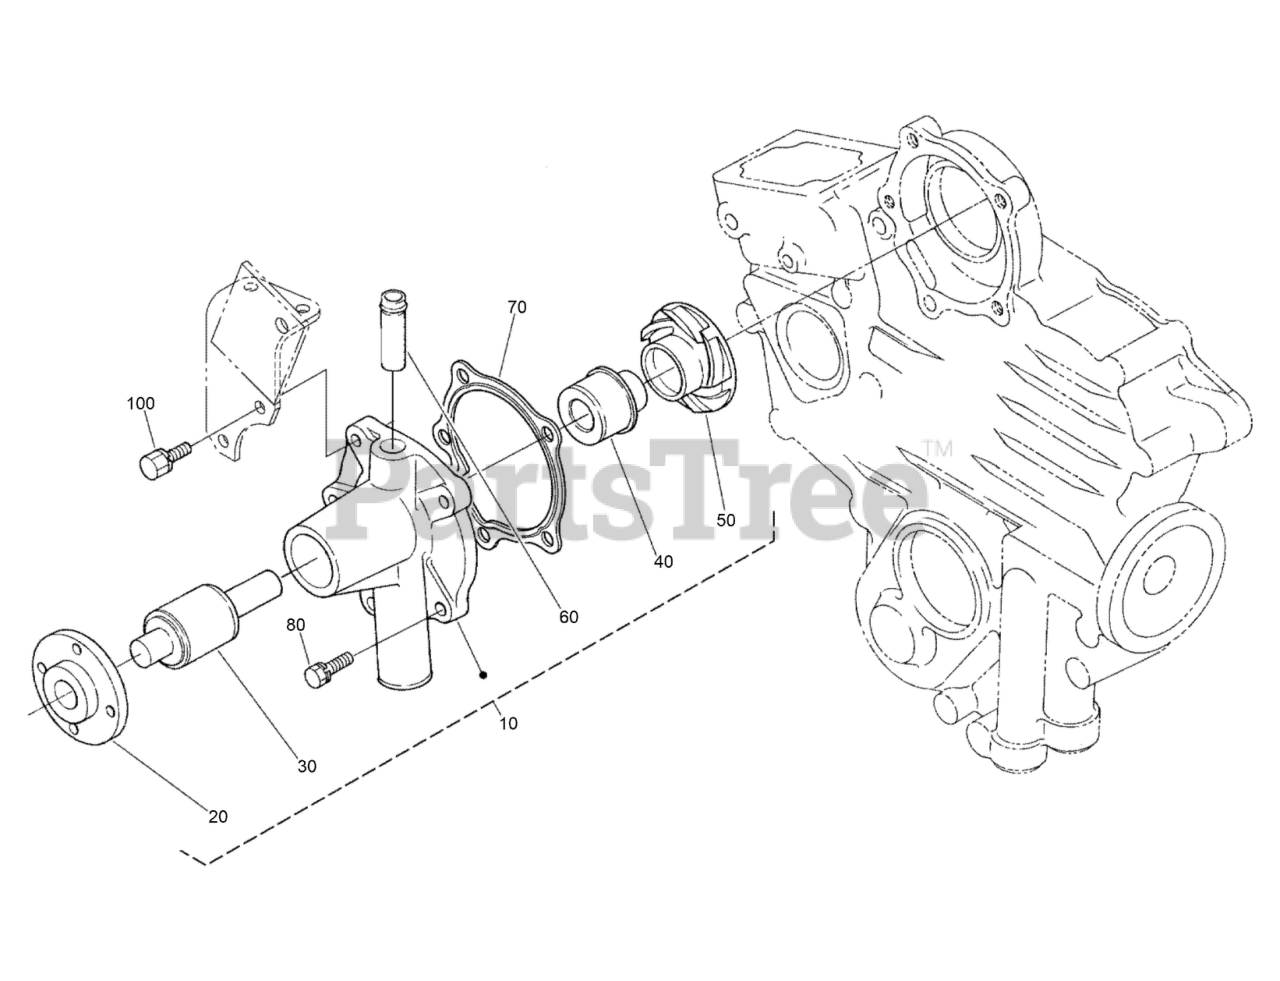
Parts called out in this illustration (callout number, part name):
10	ASSY PUMP,WATER
20	FLANGE-PUMP, WATER
30	BEARING-BALL
40	ASSY SEAL,MECHANICAL
50	IMPELLER,WATER PUMP
60	PIPE-RETURN, WATER
70	GASKET-PUMP, WATER
